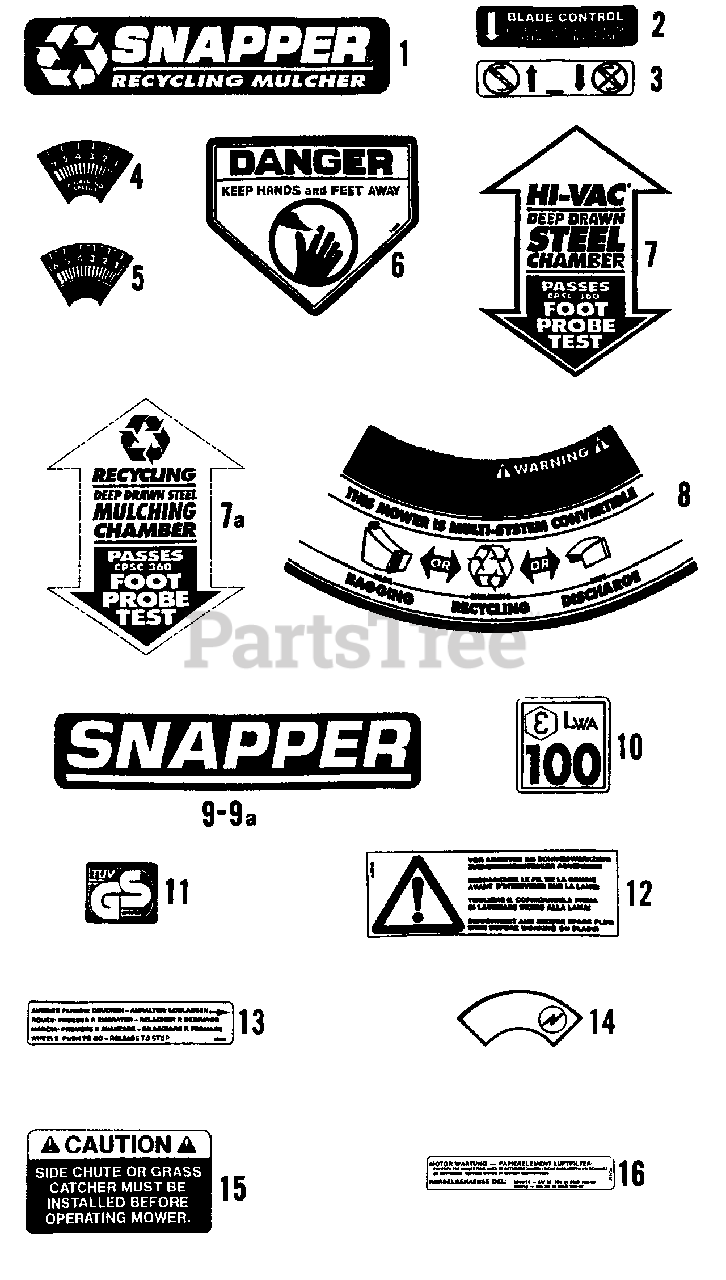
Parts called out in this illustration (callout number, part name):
1	PLATE, Recycling (Molded)
2	DECAL, Blade Control
3	DECAL, Blade Control
4	DECAL, Speed Sector
5	DECAL, Speed Sector
6	DECAL, Danger
7	DECAL, Hi-Vac/Foot Probe (Red)
7A	DECAL, Recy - Foot Probe (Green)
8	DECAL, Serial Blank (Large)
9	LOGO, Molded 7.28"
9A	DECAL, Snapper 7.31"
10	DECAL, Noise Control
11	DECAL, GS
12	DECAL, Spark Plug
13	DECAL, Wheel Control
14	DECAL, Ignition
15	DECAL, Caution Discharge Opening
16	DECAL, Air Cleaner
